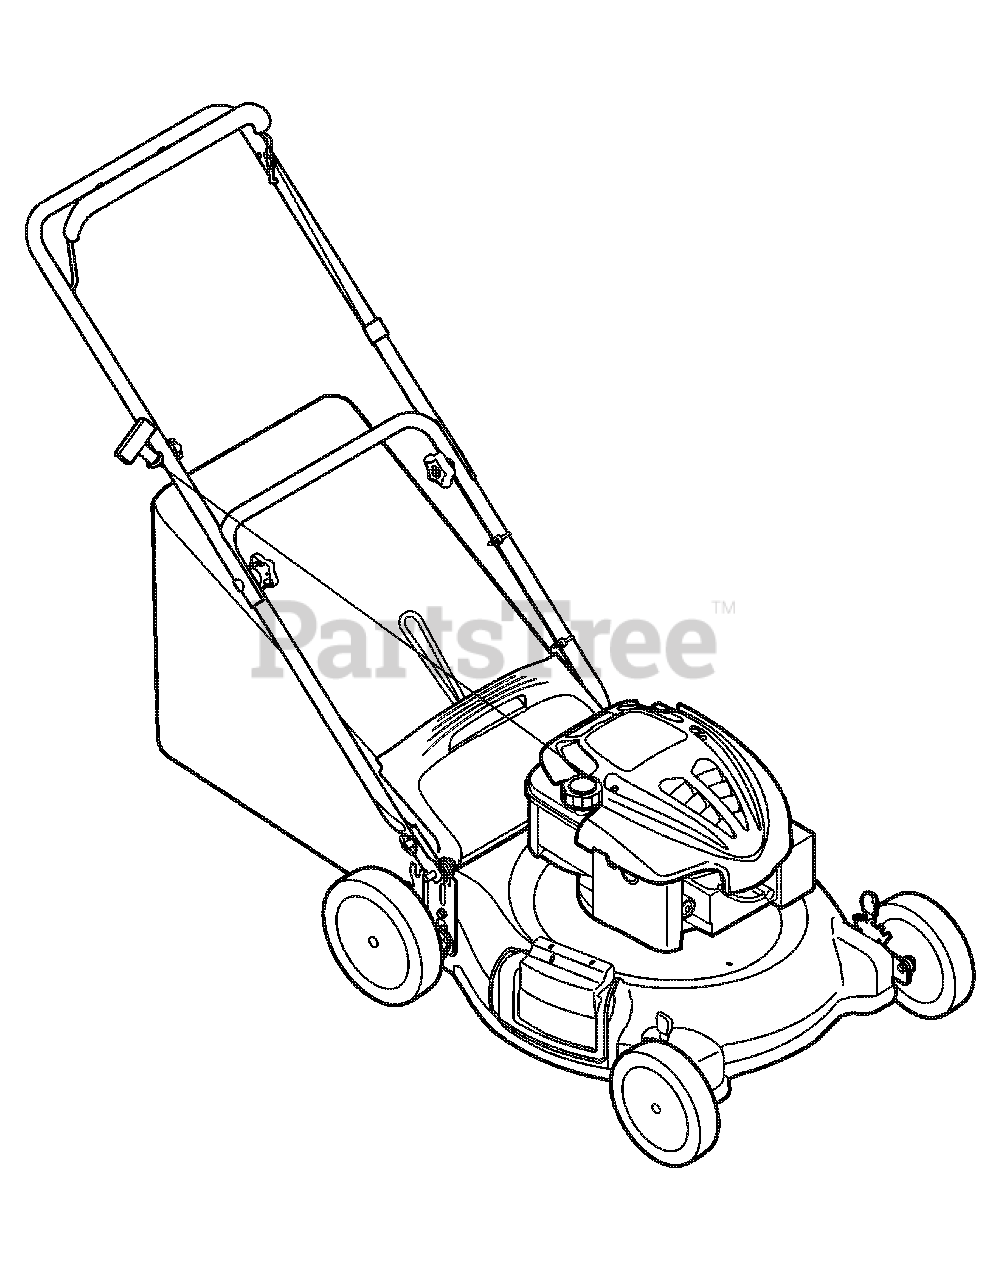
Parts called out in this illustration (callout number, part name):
NA	Drive Belt
NA	Drive Cable
NA	Ignition Key
